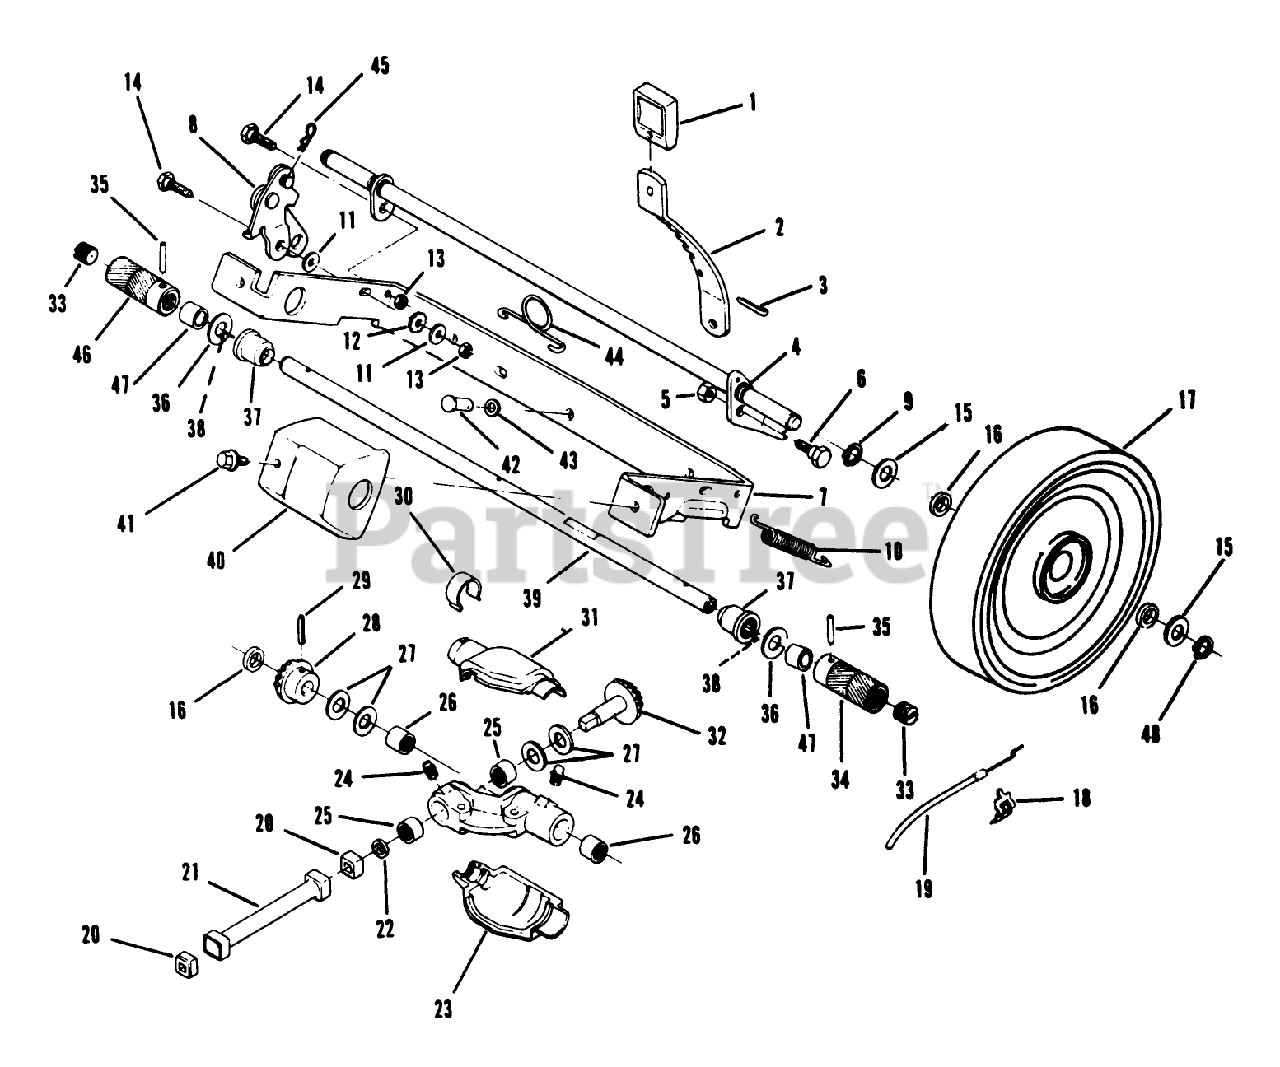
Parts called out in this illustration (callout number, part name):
1	KNOB
2	LEVER
4	AXLE & TORQUE LUG ASM
5	LOCKNUT E
6	BOLT RB&W
7	BRK-21" AXLE
9	RET RING
10	SPRING
11	WASHER S
13	STOP NUT
14	BOLT RB&W
15	SPACER
16	WASHER
20	BUSHING
22	O-RING
24	**FITTING LINCOLN
25	NEEDLE BEARING
27	THRUST WASHER
28	GEAR ADVANCE
29	ROLL PIN
31	GEAR COVER UPPER
32	GEAR BEST
33	GREASE PLUG
34	ROLLER-LEFT
35	PIN
38	BEARING AY F
39	DRIVE SHAFT & TAG
42	PIN
43	WASHER SPRING LAR
44	SPRING N.A.S
48	RET RING
